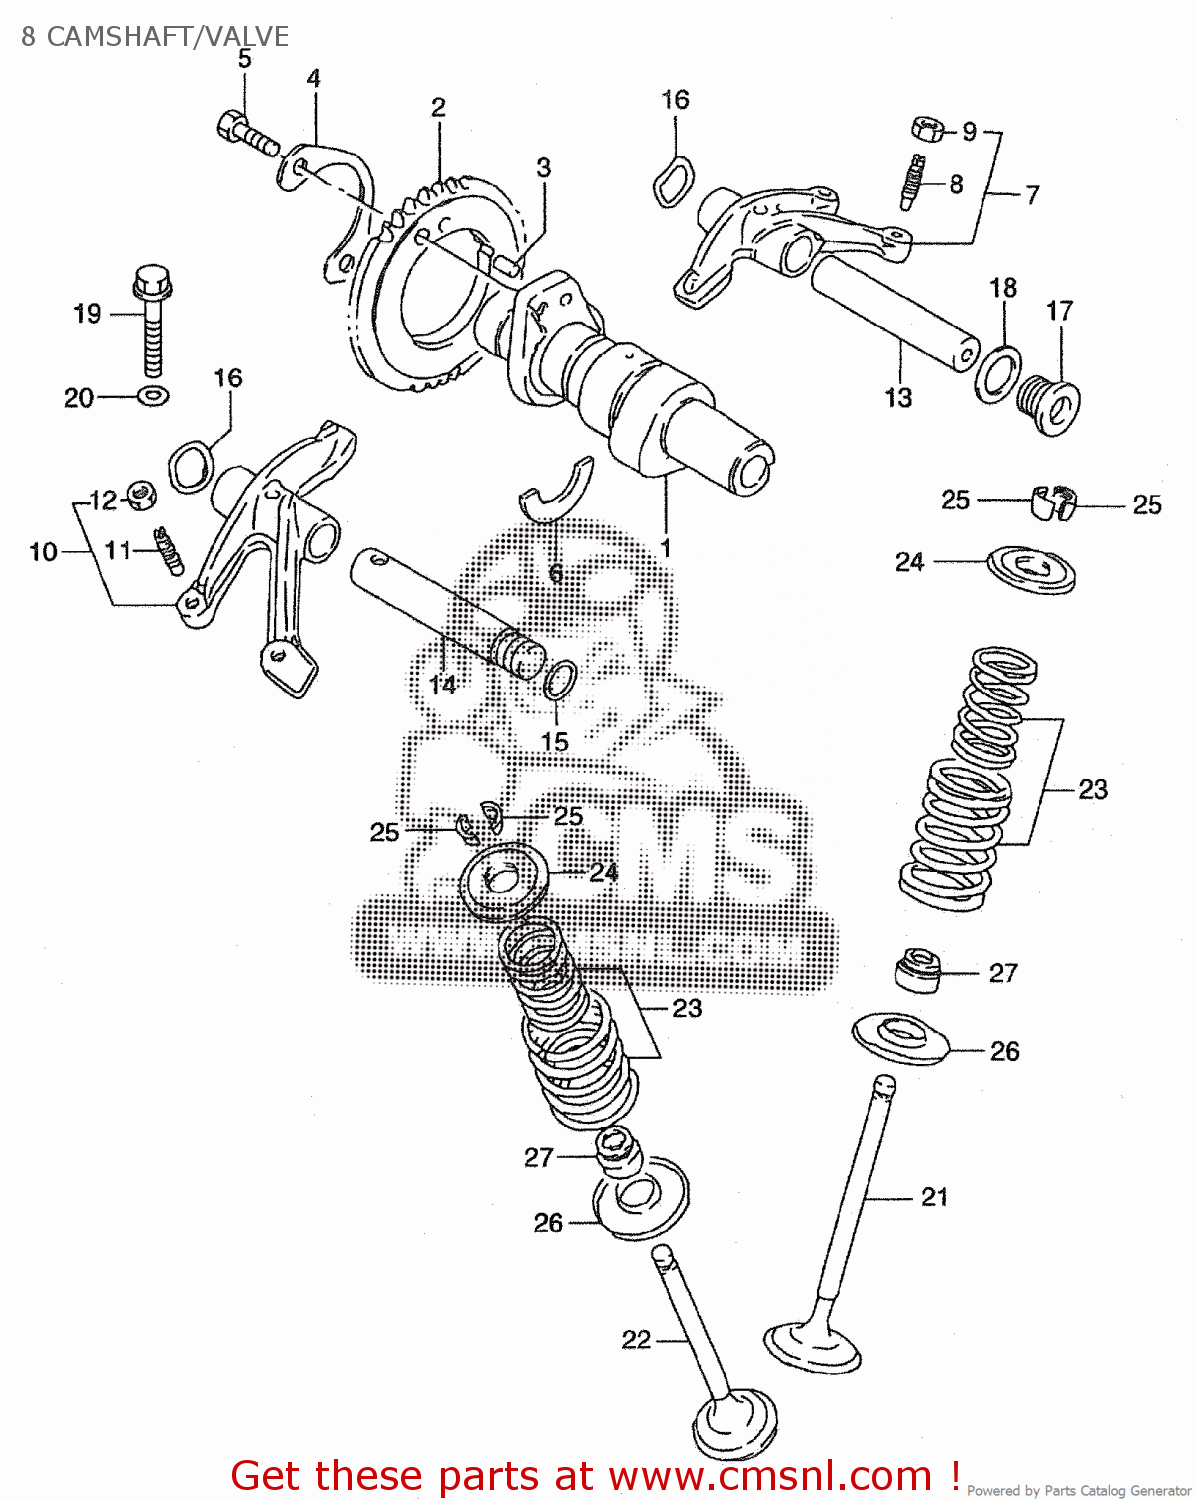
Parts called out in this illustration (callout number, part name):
1	CAMSHAFT
2	SPROCKET,CAMSHAFT
3	PIN(5X12.9)
4	WASHER,CAM CHAIN SPROCKET
5	BOLT(6X16)
6	C RING
7	ARM,INTAKE VALVE ROCKER
8	SCREW,TAPPET ADJUSTING
9	NUT,ADJUSTING SCREW
10	ARM,EXHAUST VALVE ROCKER
11	SCREW,TAPPET ADJUSTING
12	NUT,ADJUSTING SCREW
13	SHAFT,VALVE ROCKER ARM INTAKE
14	SHAFT,EXHAUST VALVE ROCKER ARM
15	O RING(D:1.9,ID:8.6)
16	WASHER
17	PLUG,14X12
18	GASKET(13.8X18.8X4.8) (NAS)
19	BOLT
20	GASKET(5.8X13X1.2) (NAS)
21	VALVE,INTAKE
22	VALVE,EXHAUST
23	SPRING SET,VALVE
24	RETAINER,VALVE SPRING
25	COTTER,VALVE
26	SEAT,VALVE SPRING
27	SEAL,OIL(7X14.4X9)
